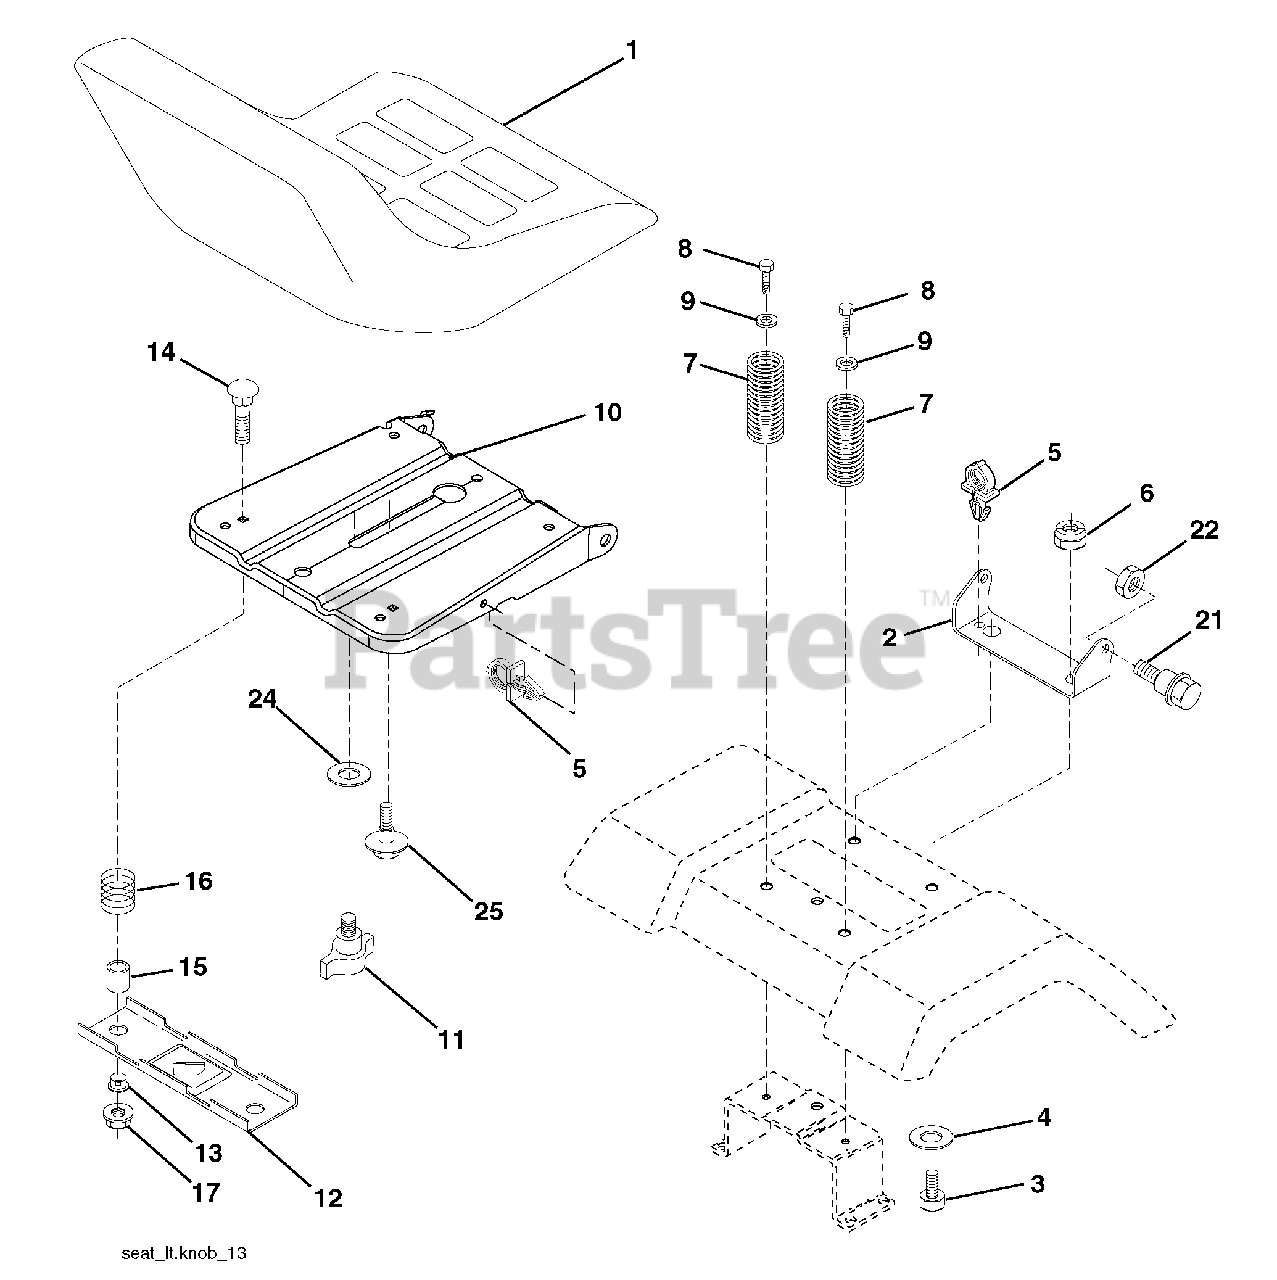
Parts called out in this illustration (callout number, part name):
1	Seat
2	Bracket Pivot Seat 8 720
3	Bolt Fin Hex 3/8-16 unc x 1
4	Washer 13/32 x 1 x 10 Ga.
5	Clip Push-In
6	Nut Hex w/Ins. 3/8-16 unc
7	Spring Seat Cprsn 2 250 Blk Zi
8	Screw 3/8-16 x 1.5 Smgml
9	Washer 13/32 x 1 x 14 Ga.
10	Pan Seat
11	Knob Seat
12	Bracket Mounting Switch
13	Bushing Snap Blk Nyl 50 Id
14	Bolt Rdhd Sqnk 1/4-20 x 1-1/2
15	Spacer Split 28x 88
16	Spring Cprsn
17	Nut Lock 1/4 Lge Flg Gr. 5 Zinc
21	Bolt Shoulder 5/16-18 unc
22	Nut Hex Lock W/Ins 5/16-18
24	Washer 17/32 x 1-3/16 x 12 Ga.
25	Bolt Shoulder 5/16-18 x 62
